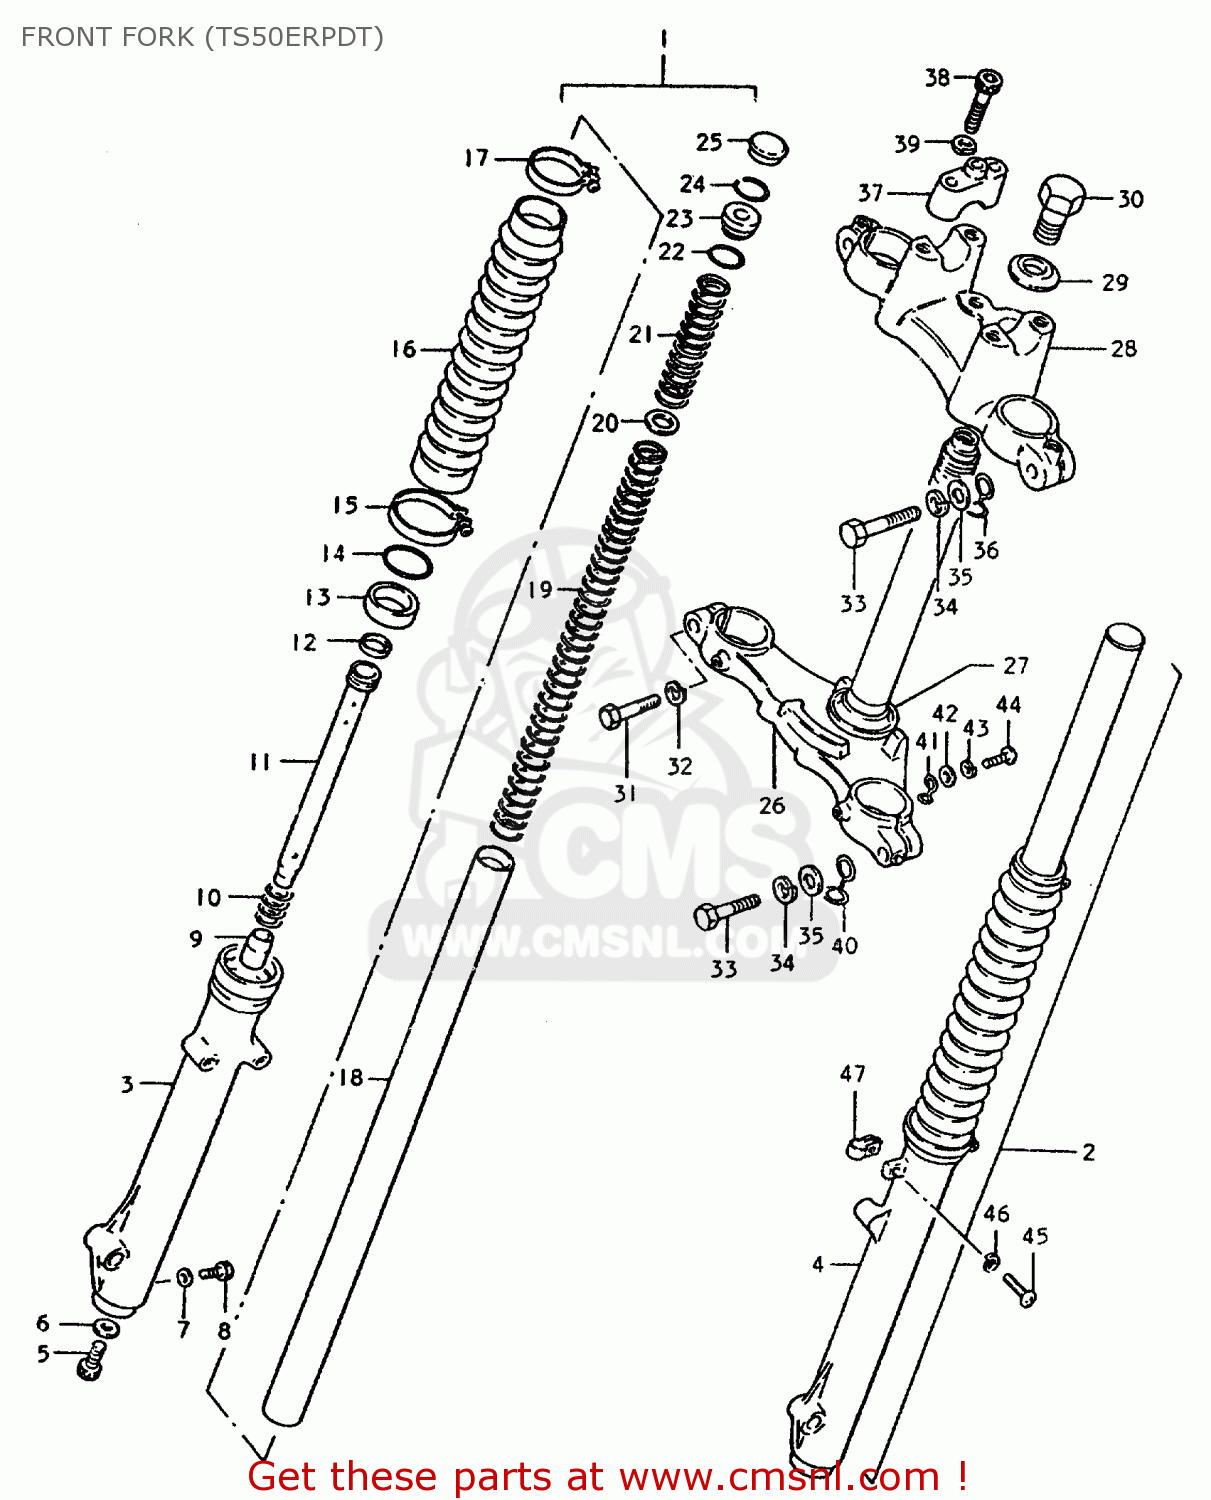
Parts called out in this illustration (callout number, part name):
1	DAMPER ASSY RH
2	DAMPER ASSY LH
3	OUTER TUBE RH
4	OUTER TUBE LH
5	BOLT(8X27)
6	GASKET (NAS)
7	GASKET,DRAIN,PLUG (NAS)
8	BOLT(6X8)
9	PIECE,OIL LOCK
10	SPRING,FORK REBOUND
11	CYLINDER,FRONT FORK
12	RING
13	OIL SEAL,FRONT FORK
14	CIRCLIP,FORK OIL SEAL
15	CLAMP
16	BOOT
17	BAND,FRONT FORK COVER BOOT
18	INNER TUBE
19	SPRING B
20	SEAT,SPRING
21	SPRING A
22	O RING
23	SEAT,SPRING
24	RING,STOPPER
25	CAP,FRONT FORK
26	STEM, STEERING
27	RACE,STEERING OUTER LWR
28	HEAD, STEERING STEM
29	WASHER(10.5X30X2.3)
30	BOLT
31	BOLT 10X25
32	LOCK WASHER
33	BOLT
34	LOCK WASHER
35	WASHER
36	CLIP
37	HOLDER,HANDLEBAR
38	BOLT 8X35
39	LOCK WASHER
40	CLIP
41	CLIP
42	WASHER
43	LOCK WASHER
44	SCREW 6X12
45	SCREW
46	LOCK WASHER
47	CLIP,FR BRAKE CABLE
